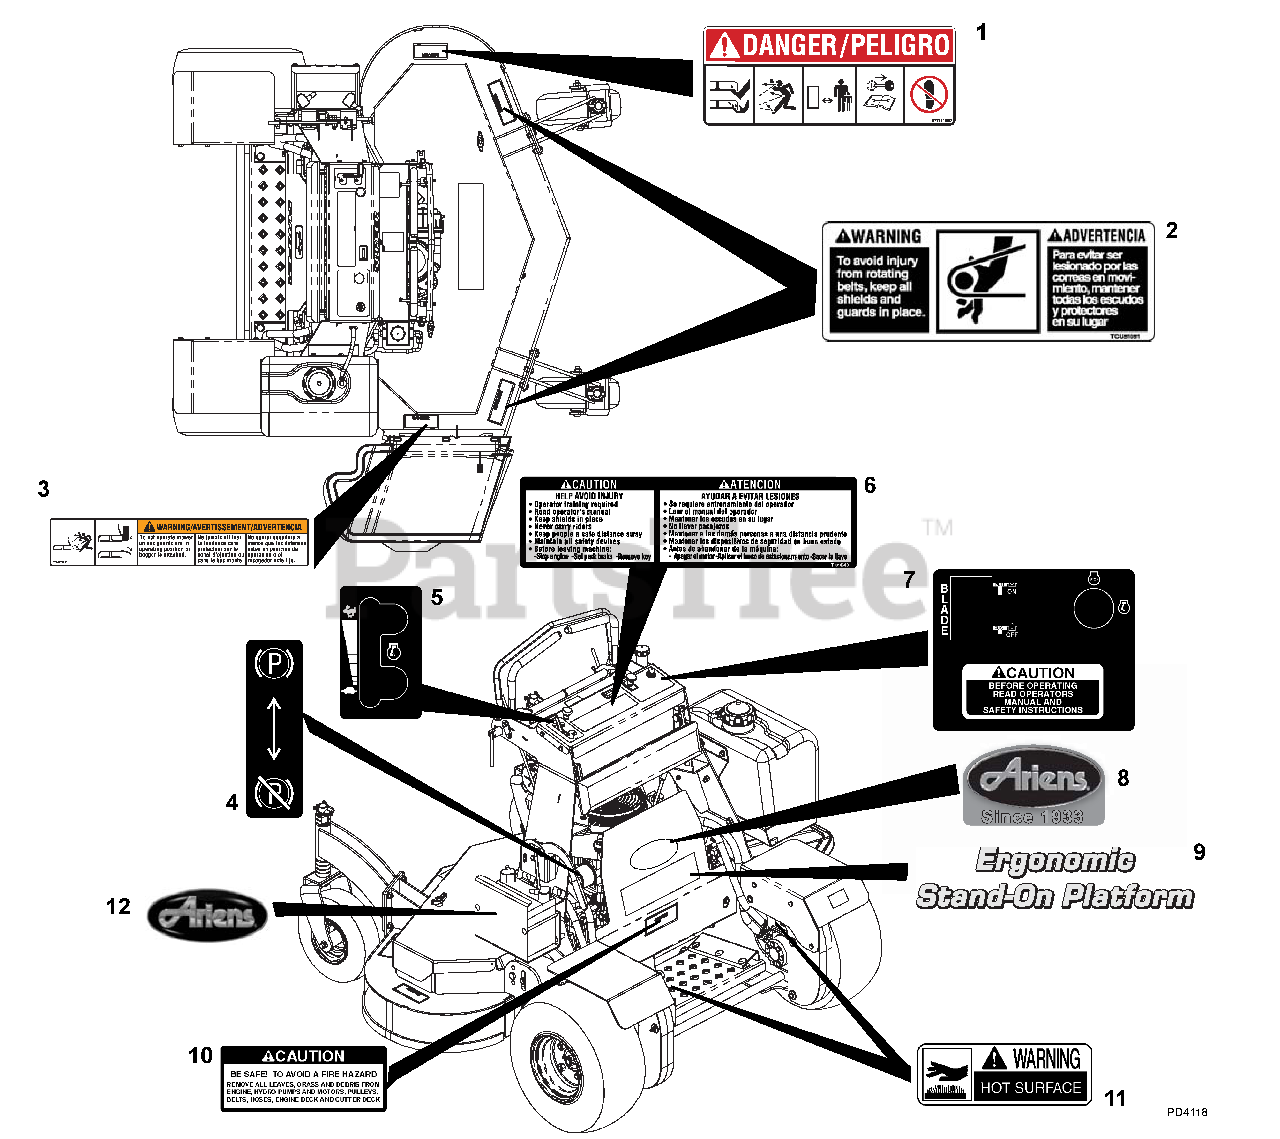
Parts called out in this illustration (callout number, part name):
1	DECAL, MOWER PAN DANGER
2	DECAL, DANGER-ROTATING BELTS
3	DECAL, WARNING
4	DECAL, PARK BRAKE
5	DECAL, THROTTLE
6	DECAL, GENERAL CAUTION
7	DECAL, PTO/IGNITION
8	DECAL-ARIENS SINCE 1933
9	DECAL, UNIT FEATURE 52 STANDON
10	DECAL, CAUTION-FIRE HAZARD
11	DECAL, WARNING-HOT SURFACE (RE
12	DECAL, ARIENS JEWEL
